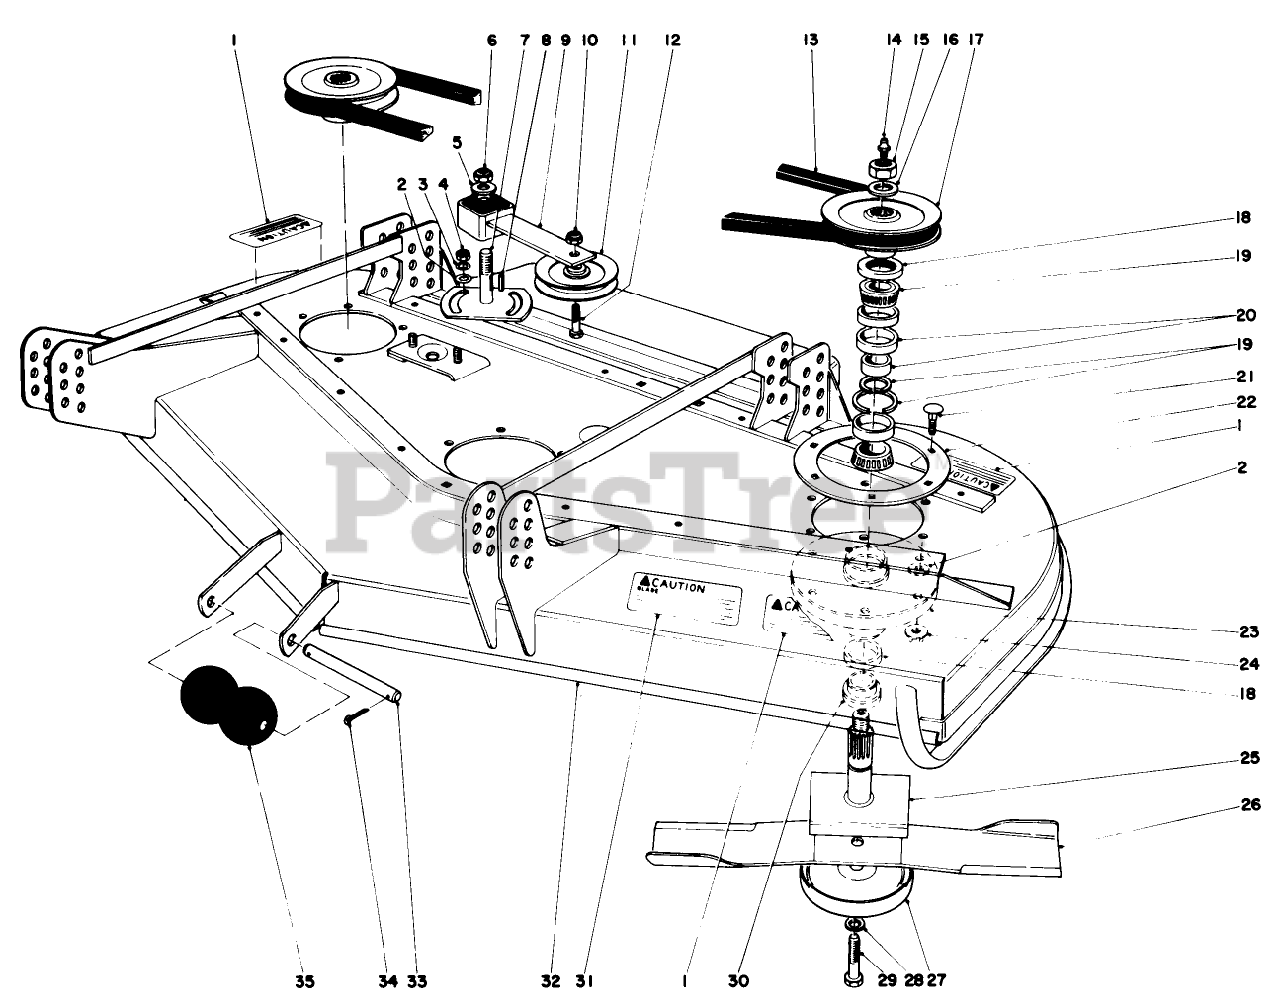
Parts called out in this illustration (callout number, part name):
1	DECAL-CAUTION, BLADE
2	WASHER-FLAT
3	WASHER-LOCK
4	NUT-JAM
5	WASHER-FLAT
6	NUT-LOCK, NI
7	PLATE-IDLER
8	KEY-SQUARE
9	IDLER ARM ASM
10	NUT-HEX
11	Idler Pulley
12	SCREW-HH
13	V-BELT
14	FITTING-GREASE
15	NUT-HEX
16	Washer
17	PULLEY AND HUB ASM
18	SEAL-OIL
19	BEARING ASM
20	SPACER-SET, MATCHED
21	SCREW-CARR
22	SUPPORT-DECK, RING
23	Housing-Spindle
24	NUT-HF
25	SHAFT
26	Blade
27	Cup-Scalp
28	WASHER-LOCK
29	Capscrew
30	SPACER
31	Decal-Caution
32	CUTTER DECK WA RO
33	SHAFT-ROLLER
34	PIN-COTTER
35	ROLLER
